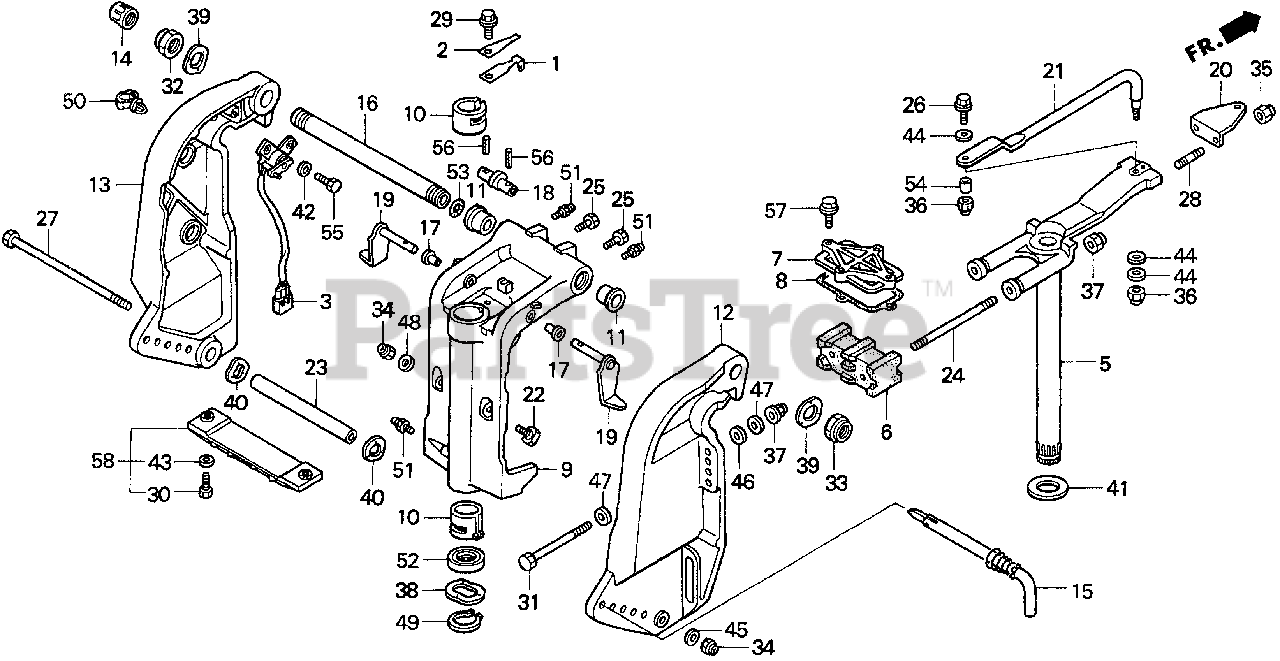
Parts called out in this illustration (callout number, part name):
1	SPRING, CLICK
2	SPRING, CLICK ASSIST
3	SENSOR ASSY., TRIM ANGLE
5	FRAME, MOUNTING *NH282MU* (OYSTER SILVER METALLIC-U)
6	MOUNT, RUBBER (UPPER)
7	HOLDER, MOUNTING (UPPER)
8	GASKET, MOUNTING HOLDER (UPPER)
9	CASE, SWIVEL *NH282MU* (OYSTER SILVER METALLIC-U)
10	LINER, SWIVEL CASE
11	BUSH, SWIVEL CASE
12	BRACKET, R. STERN *NH282MU* (OYSTER SILVER METALLIC-U)
13	BRACKET, L. STERN *NH282MU* (OYSTER SILVER METALLIC-U)
14	CAP, TILTING BOLT
15	ROD, ADJUSTING
16	SHAFT, TILTING
17	BUSH, TILT ARM
18	BRACKET, TILTING
19	STOPPER, TILT
20	PLATE, STEERING
21	ROD, STEERING
22	RECEIVER, THRUST
23	COLLAR, CYLINDER (LOWER)
24	BOLT, STUD (12X150)
25	BOLT (1/4-28UNF)
26	BOLT (3/8-24UNF)
27	BOLT, HEX. (10X235)
28	BOLT, STUD (10X28)
29	BOLT, HEX. (6X14)
30	BOLT, HEX. (6X25)
31	BOLT, HEX. (12X119)
32	NUT, SELF-LOCK (7/8-14UNF)
33	NUT, SELF-LOCK (M25X2.0)
34	NUT, SELF-LOCK (10MM)
35	NUT, SELF-LOCK (10MM)
36	NUT, SELF-LOCK (3/8-24UNF)
37	NUT, SELF-LOCK (12MM)
38	WASHER, WAVE (40MM)
39	WASHER, WAVE (26MM)
40	WASHER, WAVE (32MM)
41	WASHER, THRUST (34MM)
42	WASHER, PLAIN (6MM)
43	WASHER, PLAIN (6MM)
44	WASHER (10MM)
45	WASHER, PLAIN (10MM)
46	WASHER, PLAIN (12MM)
47	WASHER, PLAIN (12MM)
48	WASHER, PLAIN (10MM)
49	CIRCLIP (OUTER) (39MM)
50	CLIP, WIRE HARNESS
51	NIPPLE, GREASE
52	OIL SEAL (39.5X52X6)
53	O-RING (15.54X2.26)
54	COLLAR, STEERING ROD
55	BOLT, HEX. (6X20)
56	PIN, SPRING (2.5X20)
57	BOLT, FLANGE (8X30)
58	METAL KIT, ANODE
